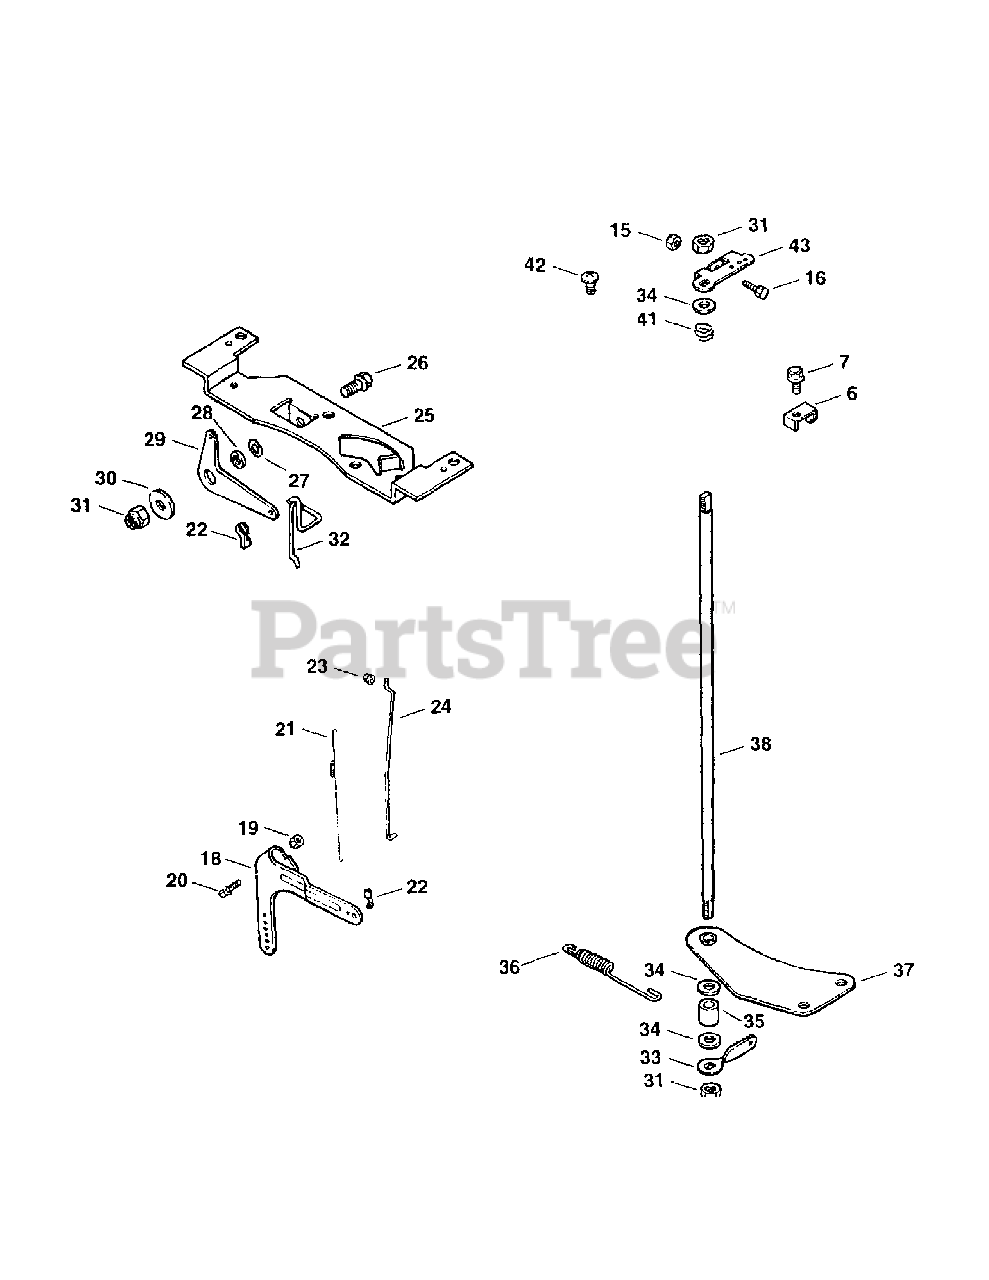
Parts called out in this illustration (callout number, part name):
6	Clamp, Cable
7	Screw, Hex Flange
15	Nut, Hex Flange
16	Screw, Hex Cap
18	Lever, Governor
19	Nut, Hex Flange
20	Screw, Hex Cap
21	Spring, Linkage
22	Bushing, Linkage (Black)
23	Bushing, Linkage (Natural)
24	Linkage, Throttle
25	Bracket, Control
26	Screw, Hex Flange
27	Washer, Spring
29	Lever, Choke
30	Washer, Plain 1/4"
31	Nut, Hex
32	Linkage, Choke
33	Lever, Throttle Control
34	Washer, Plain 1/4"
36	Spring, Governor
37	Bracket, Throttle Shaft
38	Shaft, Throttle
41	Spring, Throttle Shaft
42	Screw, Phillips Head
43	Lever, Throttle Control
